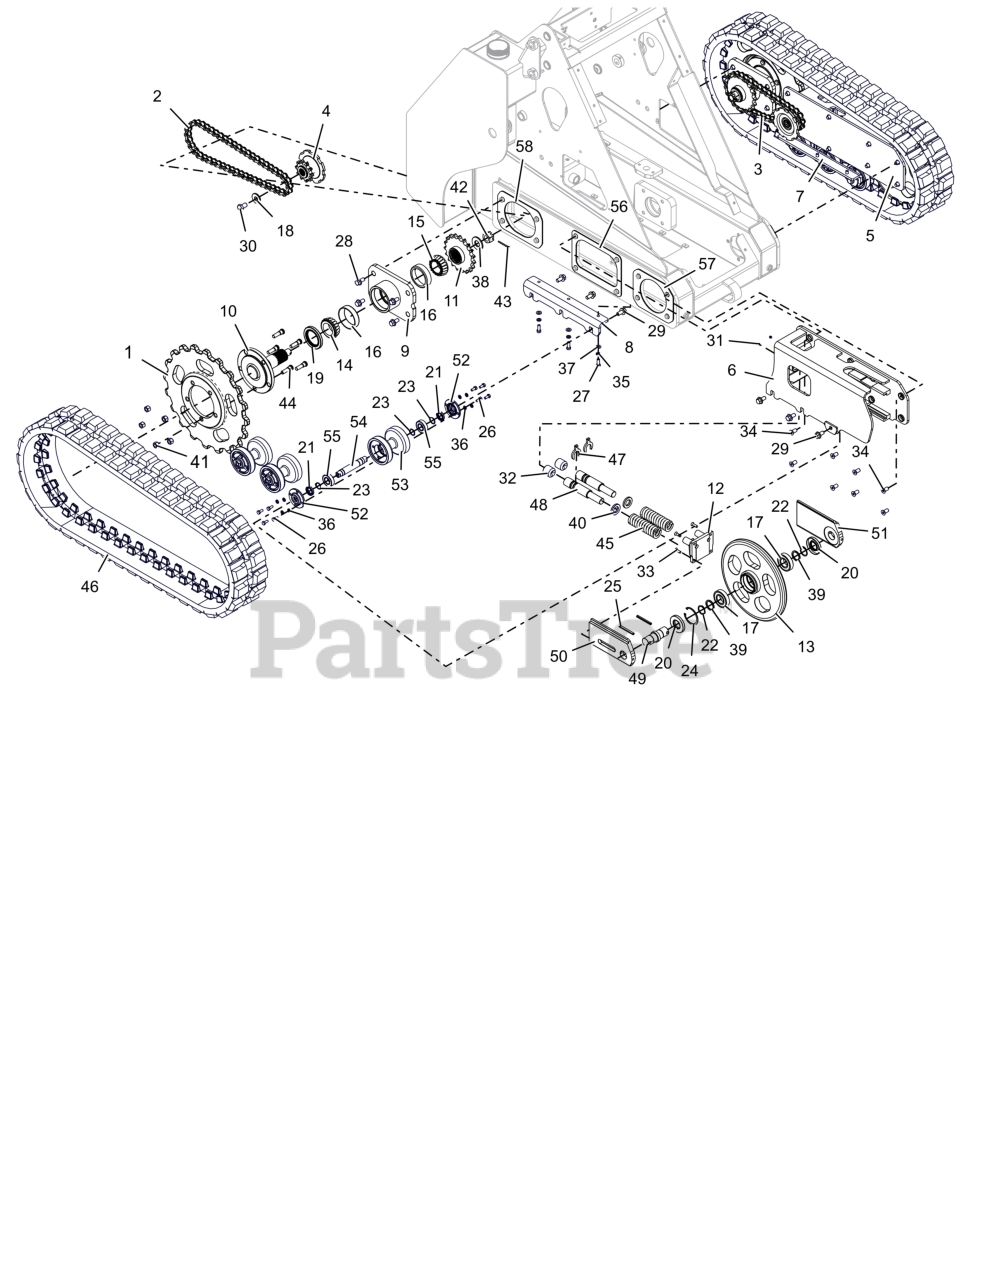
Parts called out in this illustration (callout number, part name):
1	WHEEL, DRIVE - TRACK (BLACK)
2	CHAIN, ROLLER -RS80HT 50 PITCH
3	CHAIN, ROLLER -RS80HT 38 PITCH
4	SPROCKET, DRIVE - DT
5	MOUNT, IDLER LH - TRACK NARROW
6	MOUNT, IDLER RH - TRACK NARROW
7	MOUNT, ROLLER - LH (RED)
8	MOUNT, ROLLER - RH (RED)
9	WLDMT, HUB -TRACK (RED)
10	WLDMT, AXLE - TRACK (RED)
11	SPROCKET, DRIVEN -REAR #80 19T
12	PLATE, TENSION -TRACK (BLACK)
13	WHEEL, IDLER - TRACK
14	BRG, CONE 2.063 X 1.193
15	BRG, CONE 2.000 X 1.193
16	BRG, CUP 3.672 X .938
17	BRG-BALL 1.378x2.835x.669
18	SPCR, FLANGE
19	SEAL, OIL - 2.50X3.756X.500
20	SEAL, OIL - 35MMX72MMX10MM
21	SEAL, OIL - 25MMX38MMX7MM
22	RING, RETAINING-EXTERNAL 35MM X 1.5MM
23	RING, RETAINING-EXTERNAL 25MM X 1.2MM
24	RING, RETAINING-INTERNAL
25	PIN-ROLL .312X3.00
26	BLT,HEX .31-18X.75 G5 ZCC
27	BLT, HEX .38-16X1.00 G8ZCCEP30
28	BLT, HEX-FLG 0.5-13X1 GR8 ZCC
29	BLT, HEX 0.5-20X1 G8 ZCC
30	BLT, HEX 0.625-18X1 GR5 ZCC
31	SCR-SET, .312-18X.312 CUP SS
32	SCR-SET, 1.50-6X1.500 CUP
33	SCR, MCH .312-18X1.00 SFH ZCC
34	SCR, MCH .50-13X1.00 SFH ZCC
35	WSHR,LK-REG .375X.094 ZCC
36	WSHR,LK-REG .312X.078 ZCC
37	WSHR,FLT .406X.812X.065 ZCC
38	WSHR, FLAT - HRD 1.01X2.25X.19
39	WSHR, FLAT - 1.380X1.750X.125
40	WSHR, FLAT -HRD 1.006X1.813X.25
41	NUT, WHEEL .500-20 ZCC
42	NUT, SLOTTED-1.00-14
43	PIN, CTR .18X2.00 EXTPRSQCT ZCC
44	STUD, WHEEL - .50-20 X 1.875LG
45	SPRG, COMPRESSION
46	TRACK, NARROW
47	CLIP, LOCKING (BLACK)
48	ROD, SPRG PUSHER
49	AXLE, IDLER -TRACK
50	PLATE, IDLER SIDE LH (BLACK)
51	PLATE, IDLER SIDE RH (BLACK)
52	CAP, ROLLER
53	WHEEL, ROLLER 200DTN
54	AXLE, ROLLER
55	BRG-BALL .984X2.04X.59
56	GASKET, ACCESS TRANSMISSION
57	GASKET, FRONT TRANSMISSION
58	GASKET, REAR TRANSMISSION
